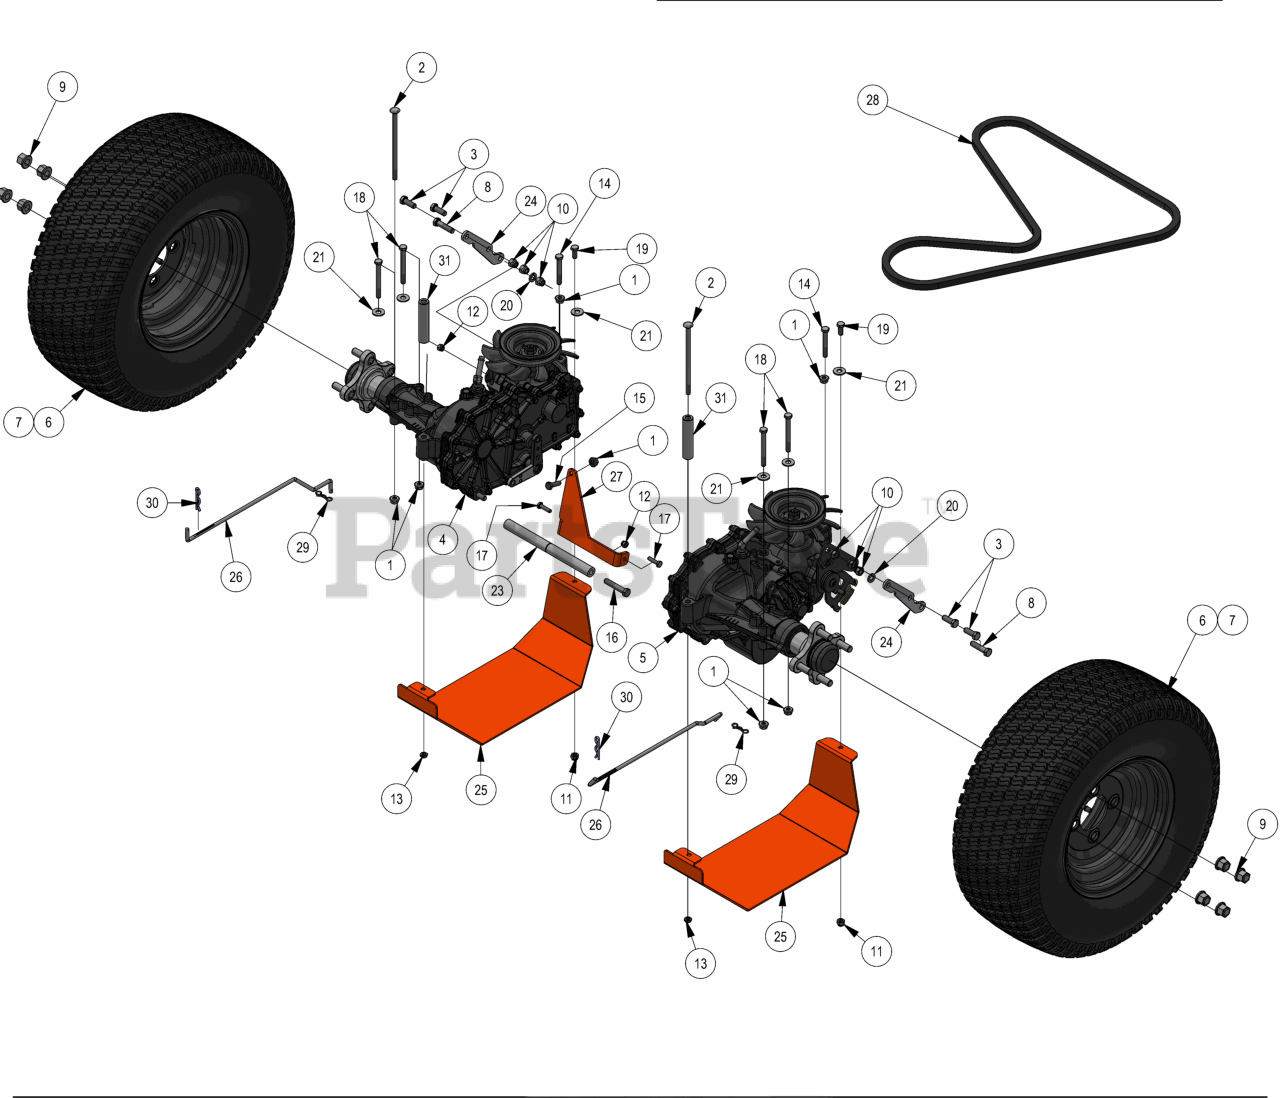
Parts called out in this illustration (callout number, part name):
1	5/16-18 NYLON INSERT FLANGE LOCKNUT ZINC
2	5/16-18 X 6 CARRIAGE BOLT (GR.5) ZINC
3	3/8-16 X 1 GR 5 Hex Bolts Zinc
4	Walk Behind Transaxle Right 3100
5	Walk Behind Transaxle Left 3100
6	Reaper Tire Assembly (21 x 8.5 - 10)
7	Reaper Tire Assembly (21x7-10)
8	3/8-16 X 1-1/2 HEX CAP SCREW (GR.5) ZINC
9	Acorn Lug Nut
10	3/8-16 NYLON INSERT LOCKNUT ZINC
11	5/16-18 NYL INS L/N ZC
12	1/4-20 NYLON INSERT LOCKNUT ZINC
13	5/16-18 NYLON INSERT JAM LOCKNUT ZINC
14	5/16-18 X 2-1/4 HEX CAP SCREW (GR.5) ZINC
15	5/16-18 X 1 HEX CAP SCREW (GR.5) ZINC
16	3/8-16 X 2 HEX CAP SCREW (GR.5) ZINC
17	1/4-20 X 1 HEX CAP SCREW (GR.5) ZINC
18	5/16-18 X 3 HEX CAP SCREW (GR.5) ZINC
19	5/16-18 X 3/4 HEX CAP SCREW (GR.5) ZINC
20	3/8 SPLIT LOCKWASHER ZINC
21	5/16 USS FLAT WASHER (7/8 OD) ZINC
23	2017 Transaxle Spacer-Walker
24	2020 Walk-Behind Hydro Plate Extension
25	2020 Walk Trans Skid Plate
26	2023 Walk Neutral Rod 5.9
27	Walk Brake Pull Bracket-Painted
28	2020 Walk-Behind Pump Belt
30	Neutral Rod Clip
31	2017 Transaxle Spacer
